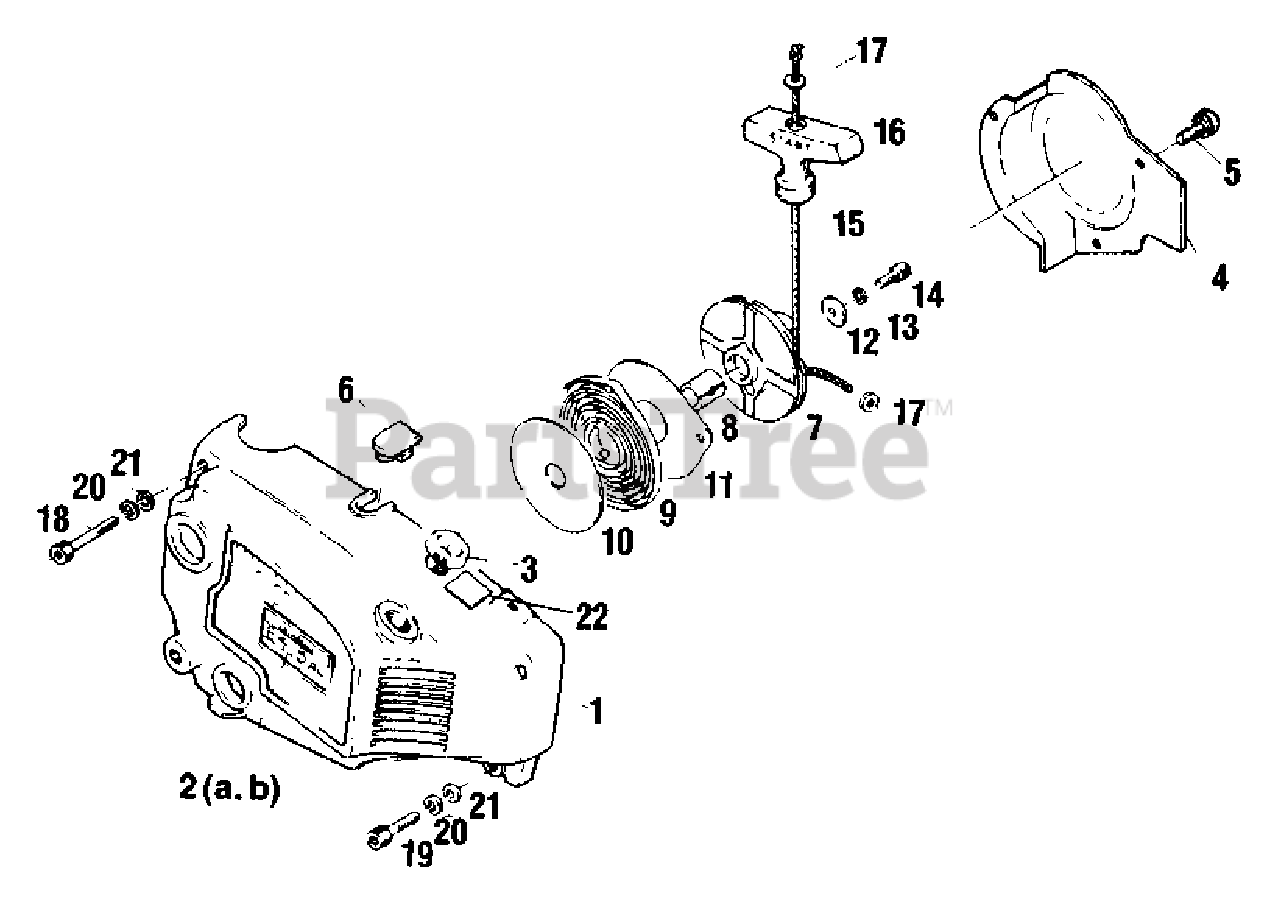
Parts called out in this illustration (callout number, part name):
1	CASE, STARTER
2A	NAME PLATE (B)
2B	NAME PLATE (B)
4	DEFLECTOR, AIR
5	SCREW
6	PLUG, RECOIL
8	BUSHING, REEL
9	RECOIL SPRING
10	PLATE (A)
11	PLATE (B)
12	WASHER
13	WASHER, SPRING 4 MM
14	BOLT 4×10
15	ROPE
16	KNOB, RECOIL
17	KNOB, STOPPER
19	BOLT M4×24
20	WASHER, SPRING 4 MM
21	WASHER 4 MM
22	CAUTION PLATE (A)
